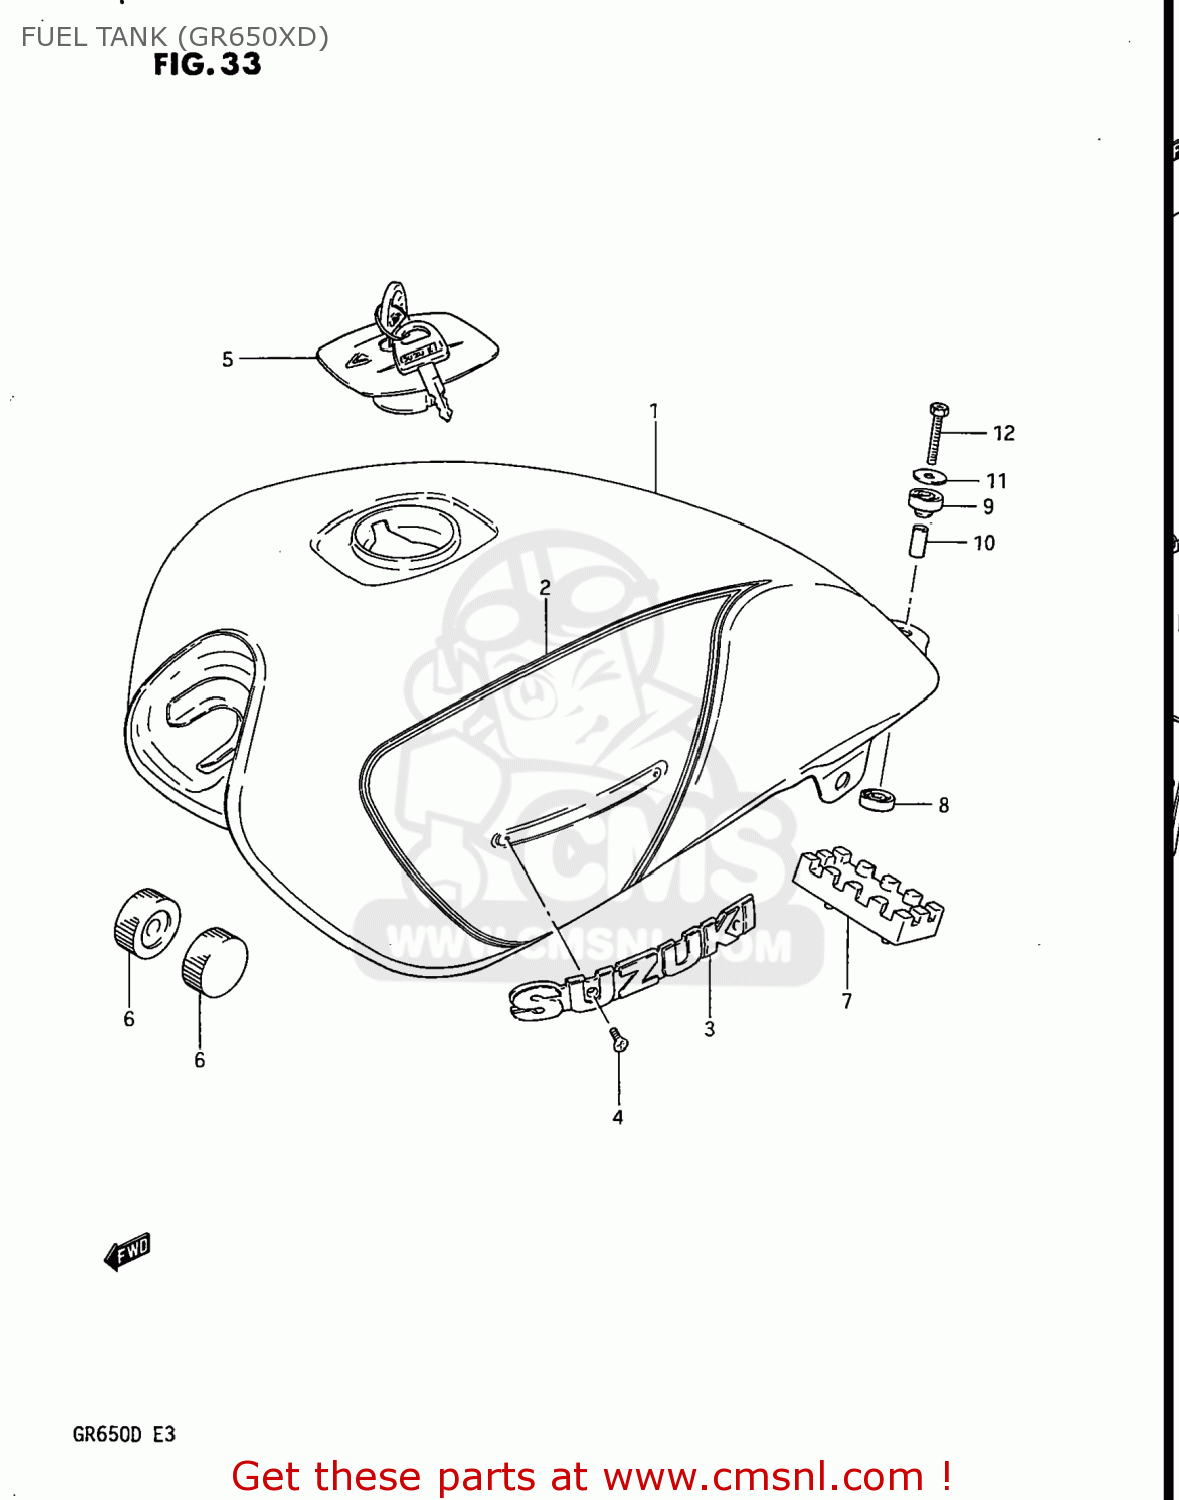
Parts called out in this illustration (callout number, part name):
1	TANK ASSEMBLY,FUEL
2	TAPE SET,FUEL TANK
3	EMBLEM,FUEL TANK
4	SCREW 3X6
5	CAP SET,FUEL TANK
6	CUSHION
7	CUSHION,FUEL TANK CTR
8	CUSHION
9	CUSHION
10	SPACER
11	WASHER (6.5X24X1.6)
12	BOLT
